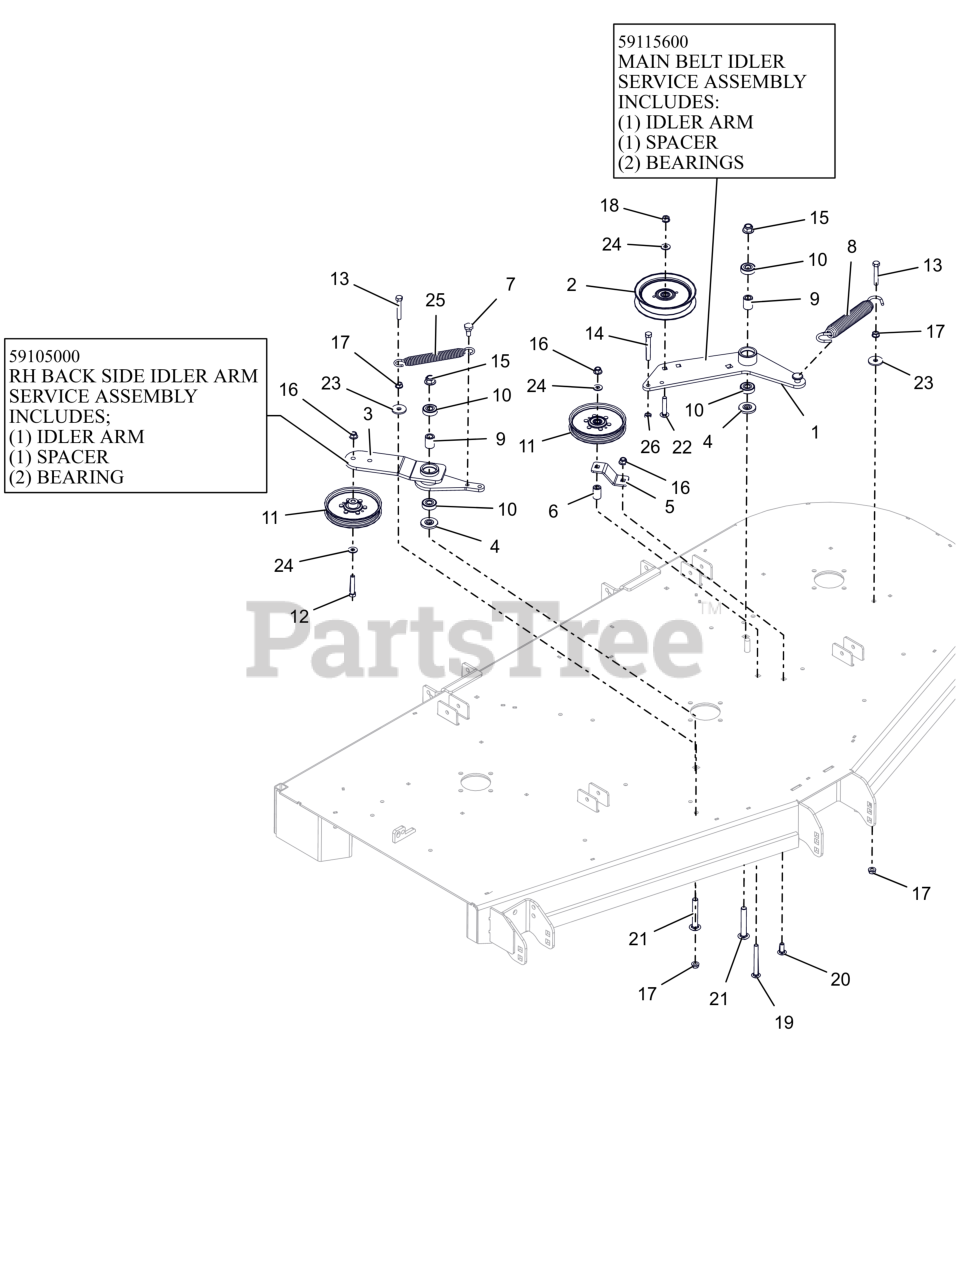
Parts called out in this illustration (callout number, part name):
1	WLDMT, DECK PTO IDLR ARM
1	ASSEMBLY, MAIN BELT IDLER
2	IDLER, FLAT 5.00"
3	WLDMT, DECK RH IDLER ARM
3	RH BACKSIDE IDLER ARM ASSEMBLY
4	SPACER, IDLER ARM
5	PTO FIXED IDLER MTG BRKT -RED
6	BUSHING, SLV .380X.750X1.190
7	BLT,SHLDR EP .38-16X.30 HEX YZ
8	SPRING, EXTENSION
9	SPACER .510 X .75 X 1.1485
10	BRG-BALL .500X1.38X.437
11	PULLEY, FLAT IDLER
12	BLT,HEX .38-16X2.00 G5 ZCC
13	BLT,HEX .38-16X2.25 G5 ZCC
14	BLT, HEX .38-16X2.75 G5 ZCC
15	NUT,NYL-FLG .50-13 GF ZCC
16	NUT,NYL-FLG .38-16 GF ZCC
17	NUT, SPNLK-FLG .38-16 G5 ZCC
18	NUT-LK-CTR-FLG .375-16 GF ZCC
19	BLT,RHSSN .38-16X3.50 G5 ZCC
20	BLT,RHSSN .38-16X1.00 G5 ZCC
21	BTL,RHSSN .500-13 X 3.25 G5 ZCC
22	BLT,RHSSN.375-16X2.00 G5 ZCC
23	WSHR,FLT .406X1.375X.135 ZCC
24	WSHR,FLT .375X.875X.083 ZCC
25	SPRING, EXTENSION
26	NUT-JAM .375-16 G2 ZCC
